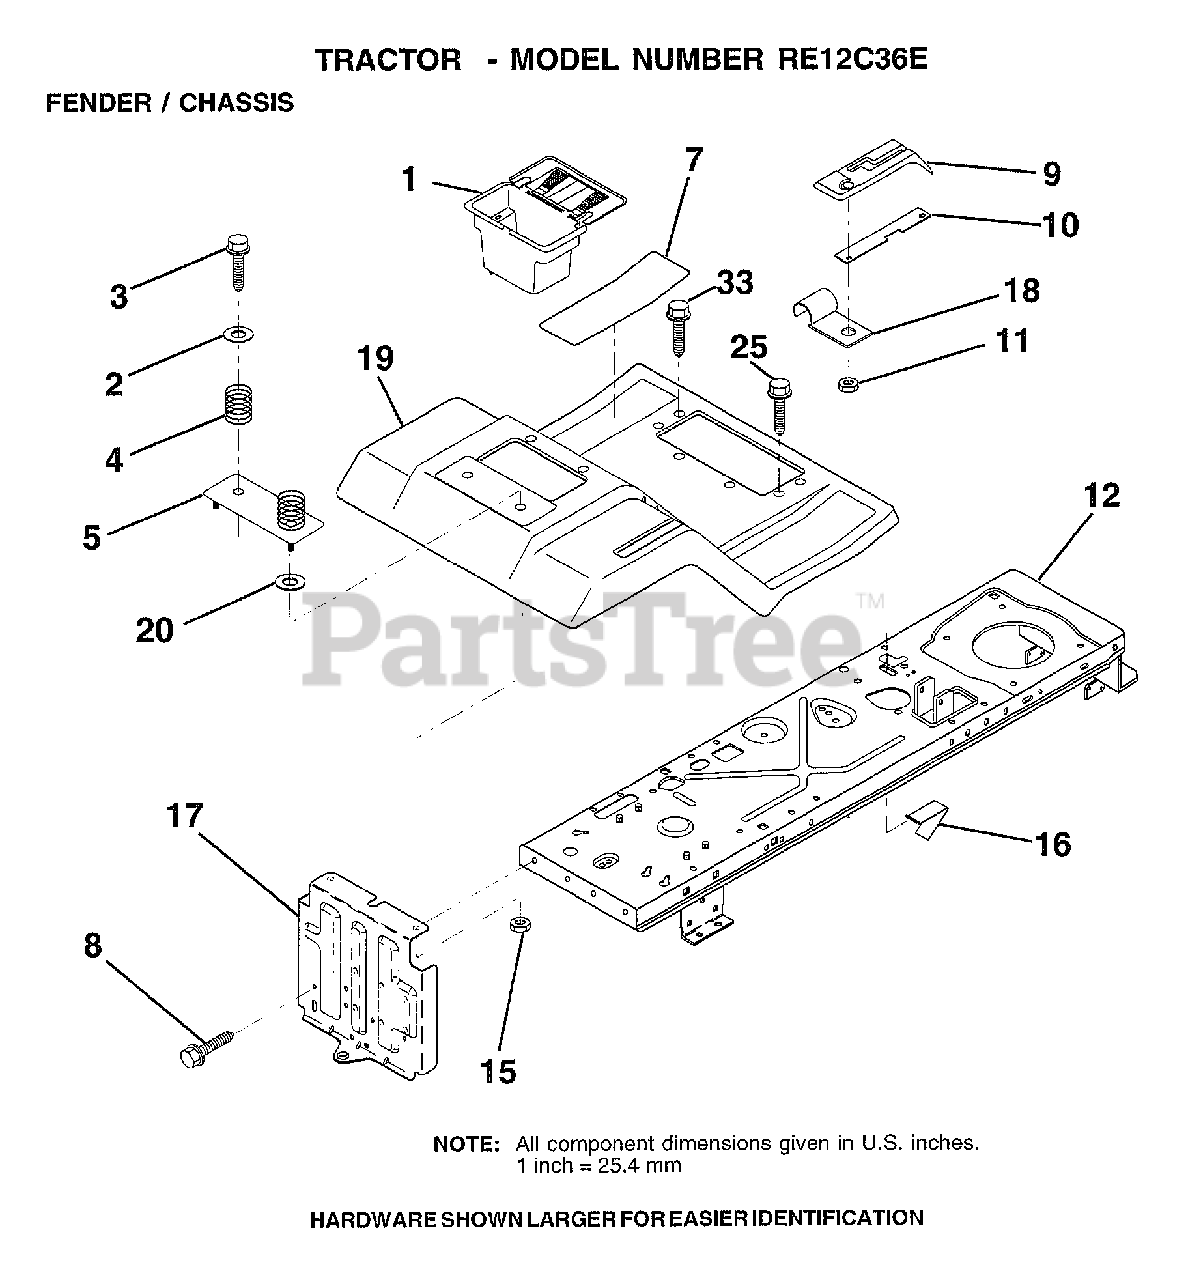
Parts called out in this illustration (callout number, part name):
1	"CASE,BATTERY.MECH"
2	WASHER
3	SCREW
4	SPRING COMPRESSIO
5	BTRY FENDER PLATE
7	PAD FOOTREST
8	SCREW
9	CONSOLE.SHIFT CONTROL
10	PLATE LOCK SHIFT
11	NUT
12	CHASSIS.WELD.ASM.
15	NUT HXKEP 1/4X20
17	DRAWBAR ASM LR
18	"CLIP,INSULATOR"
19	FENDER/FOOT MS505
25	SCREW TAPPING
33	SCREW
